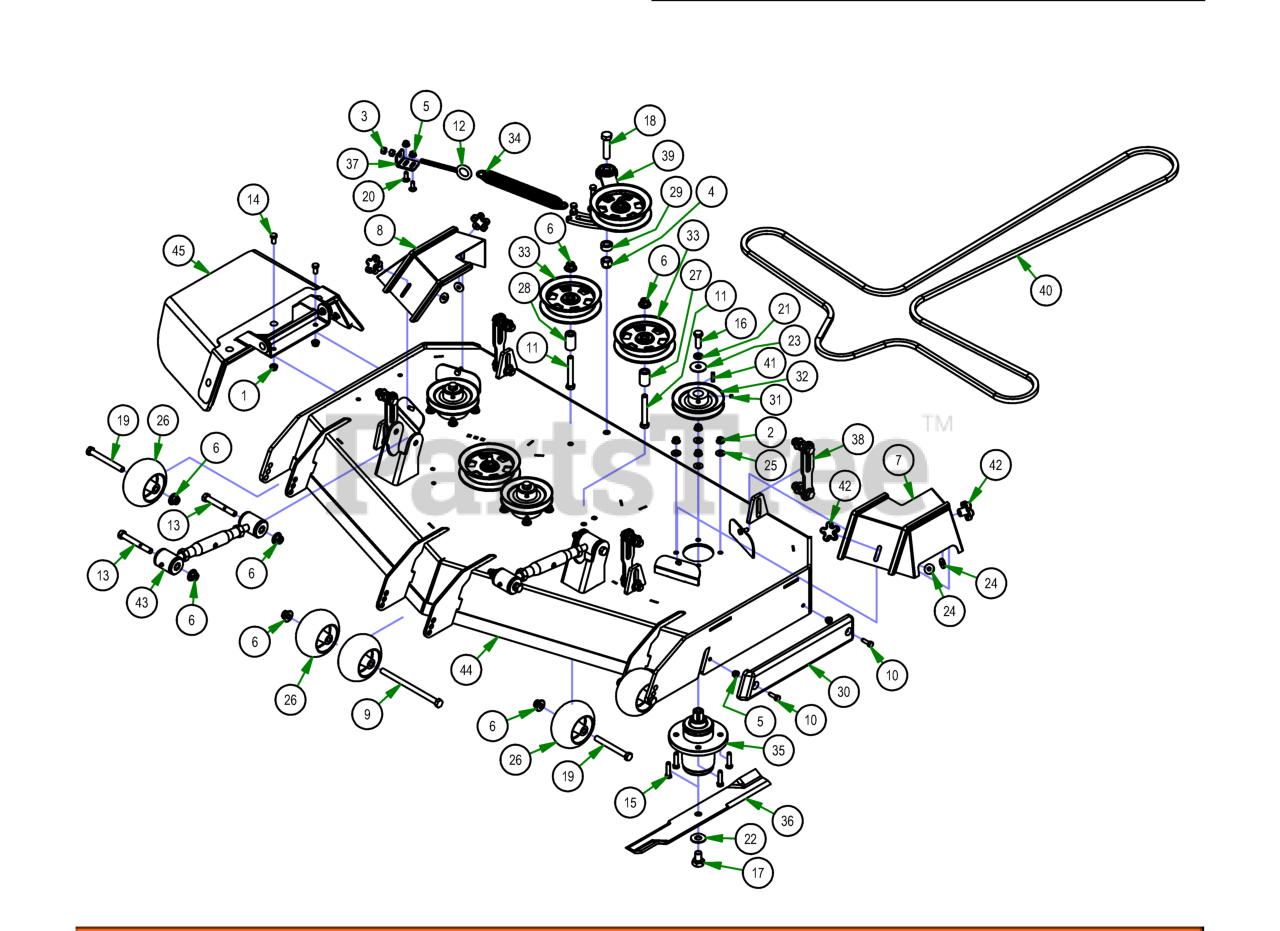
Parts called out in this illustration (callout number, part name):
1	3/8" Flange Nut
2	3/8-16 NYLON INSERT FLANGE LOCKNUT (GR.F) ZINC
3	3/8" Hex Nut
4	5/8 Std NC Nylock Nut
5	5/16" Nylon Flange Nut
6	1/2-13 NYLON INSERT FLANGE LOCKNUT ZINC
7	2019 54" Left Outlaw Gen2 Pulley Cover
8	2019 54" Right Outlaw Gen2 Pulley Cover
9	1/2-13 x 8 Hex Bolt Grade 5
10	5/16-18 x 1 GR 5 Hex Bolt Zinc
11	1/2 x 3 1/2 Flange Bolt Grade 8
12	4" 3/8-16 Eye Bolt
13	1/2" x 4" Bolt (Grade 8)
14	3/8" x 3/4" Hex Bolt
15	3/8-16 X 1-1/2 HEX CAP SCREW (GR.5) ZINC
16	1/2"-20 x 1 1/2 - Grade 5 Fine Thread Bolt
17	5/8" x 1 1/2" Grade 8 Hex Bolt (Fine)
18	5/8" x 2 1/2" Grade 5 Hex Bolt (Coarse)
19	1/2" x 4 1/2" Bolt
20	5/16" x 7/8" Carriage Bolt
21	1/2" Lock Washer
22	5/8'' Flat Washer
23	1/2" Belleville Washer
24	.360 ID Plastic Washer-Black
25	5/16 USS FLAT WASHER (7/8 OD) ZINC
26	2019 Deck Wheel
27	.502 ID X .750 OD X 1.500 Long Spacer
28	1 3/4" Pulley Spacer
29	5/8" x 1/" Collar W/One Set Screw
30	REVISED TRIM BUMPER_20180226
31	5/16 Set Screw
32	5.25" Deck Spindle Pulley
33	5-3/4 Idler Pulley
34	2019 Outlaw Gen2 Deck Spring
35	OUTLAW SPINDLE ASSEMBLY
36	54" Fusion Blade for ZT/Mav/Outlaw/Revolt
37	2019 Deck Eye Bolt Tab
38	Deck Hangar Assembly
39	2019 Rebel Rogue Deck Idler
40	B165 Belt-60 54" deck Outlaw
41	1/4" x 1" Key
42	5/16" Knob
43	Turnbuckle
44	2019 Sloped 54" Deck
45	2019 Outlaw Gen2 Chute Assembly
